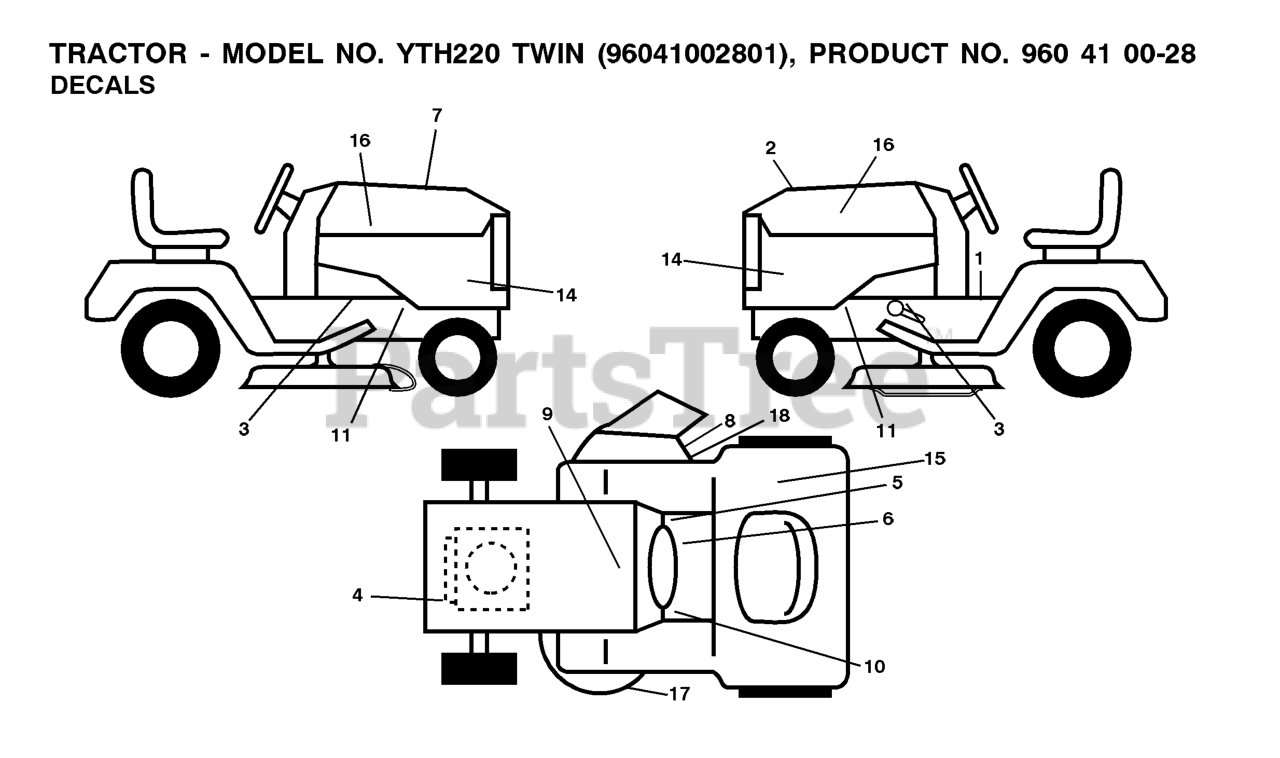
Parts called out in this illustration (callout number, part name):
1	LABEL
2	DECAL.HOOD.TOP.INSERT.
4	DECAL
5	DECAL PARK BRAKE
6	DECAL
7	DECAL RPL KO
8	DECAL.INTERNATIONL.CUTFINGER
9	DECAL BTRY SYMBOLS
10	DECAL
14	DECAL PNL SD.
15	DECAL.FENDER
16	DECAL.HOOD.NAMELOGO.HUSQ
17	DECAL.MOWER.SCH.48/54
18	DECAL, DEFLECT WARNING
